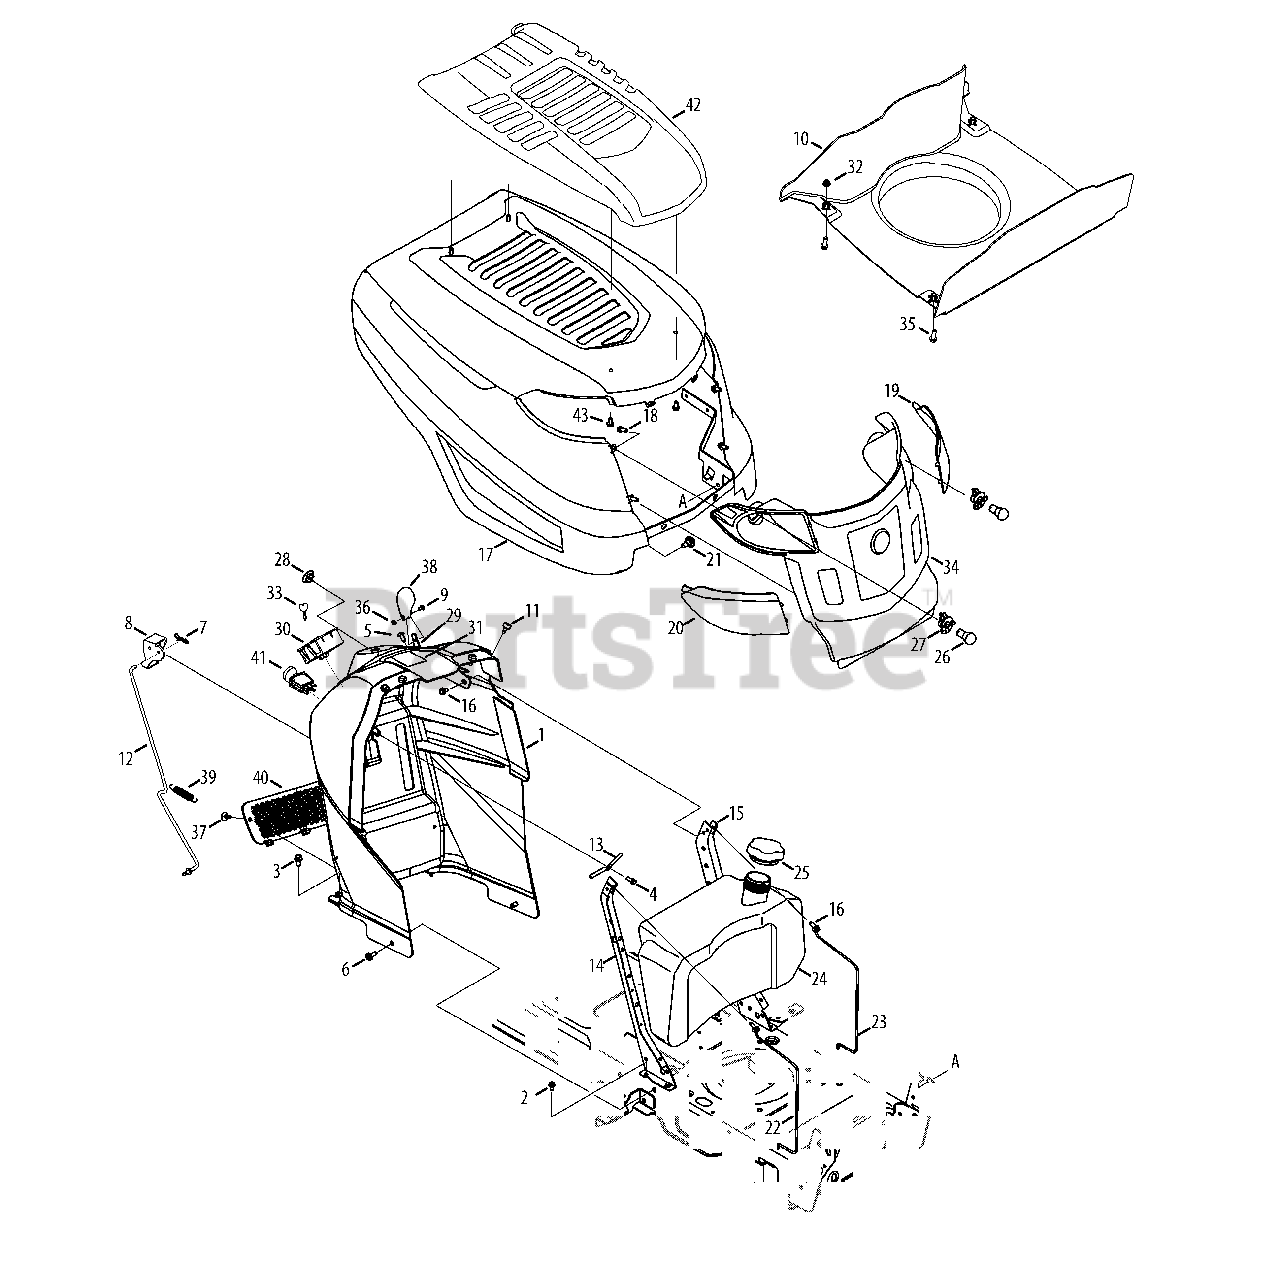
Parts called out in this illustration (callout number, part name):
2	Taptite Screw ,1/4-20:0.500
3	Taptite Screw ,5/16-18:.750
4	Hi-Lo Screw, 1/4-15:0.750
5	Screw, 1/4-14:0.625
6	Taptite Screw ,5/16-18:0.750
7	Bow Tie Cotter Pin
9	Machine Screw, #8-32:0.375
12	Control Rod Latch
14	RH Support Plate
15	LH Support Plate
16	Tap Screw, 1/4-20, 0.625
17	Hood Assembly
18	Screw, 1/4 DIA:.750
21	Shoulder Screw, .43 x .29
22	LH Tank Support Rod
23	RH Tank Support Rod
27	Lamp Socket
28	Choke Plug
29	Throttle/Choke Cable, 46.5"
30	Key Switch Module
31	Hour Meter
32	Flangelock Nut, 1/4-20
33	Key, Assembly
35	Hex Screw, 1/4-20:.620
36	Hex Nut, #8-32:GRA
37	Ratchet Clip:.250 DIA
38	Control Knob
39	Extension Spring, .500 DIA X 2.733 LG
40	Accessory Net
41	Electric PTO Switch
43	Hex Washer Screw, 1/4-15 x .50
